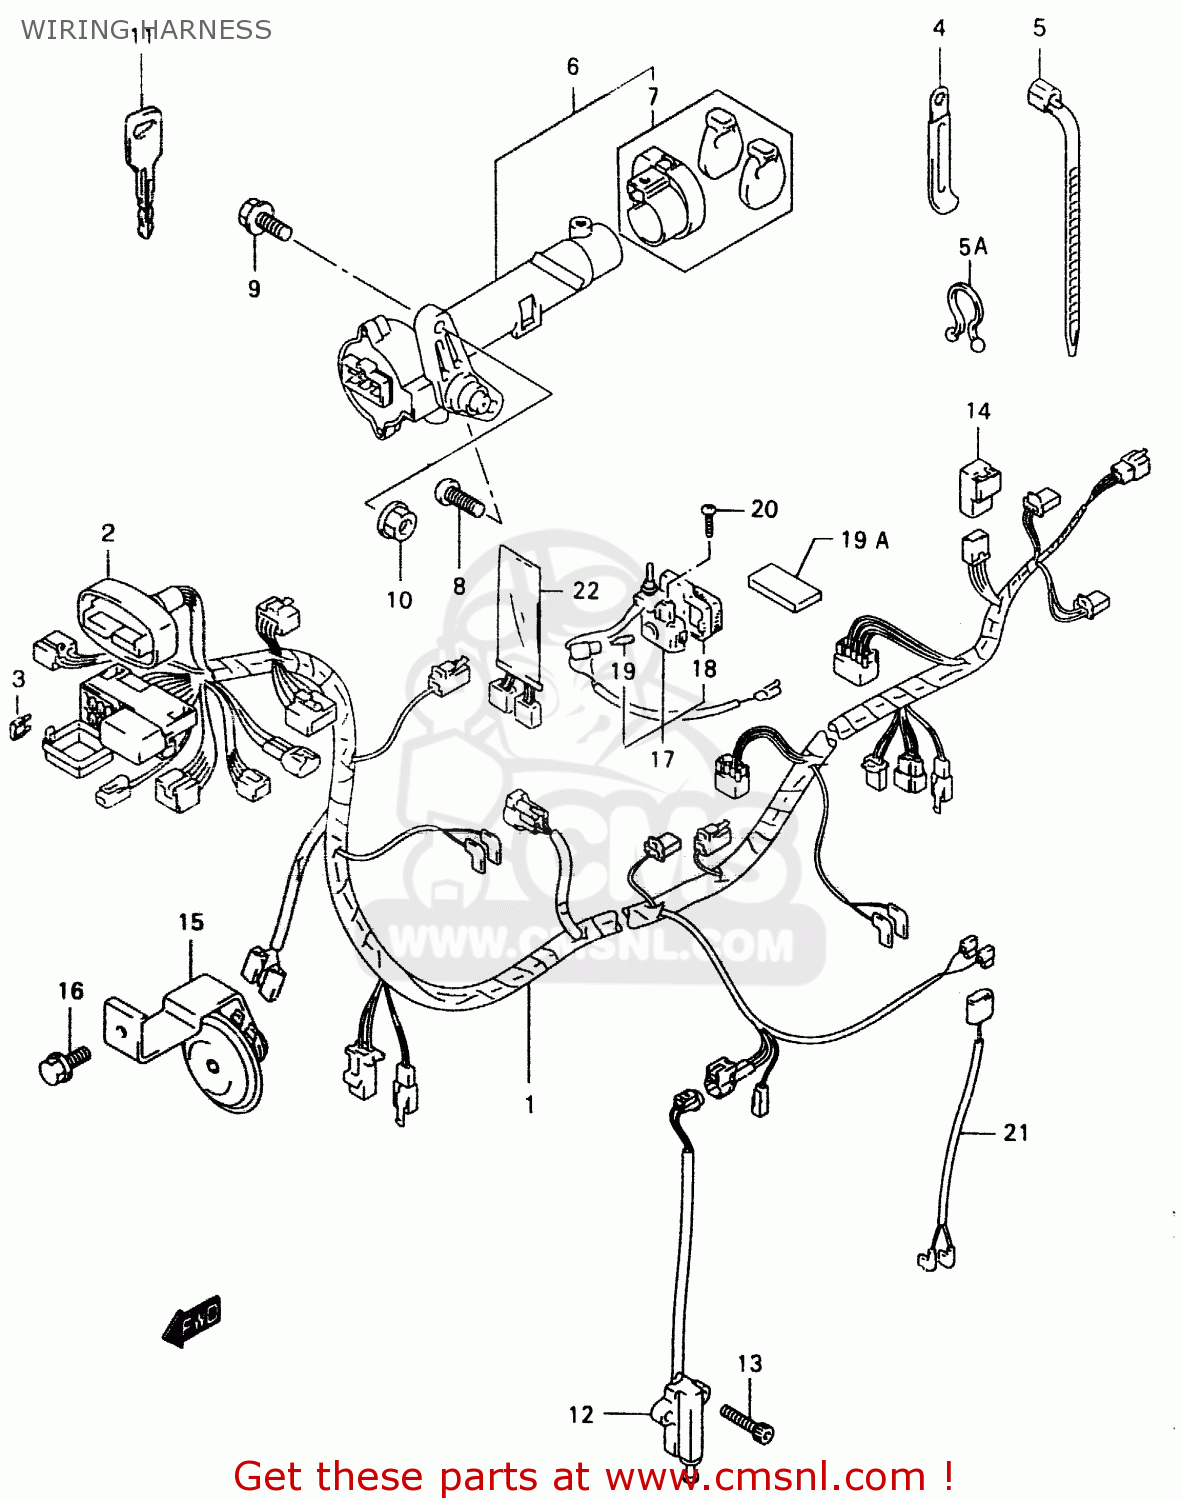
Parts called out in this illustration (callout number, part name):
1	HARNESS, WIRING
2	BOOT,METER COUPLER
3	FUSE(10A)
4	CLAMP(L:80)
5	CLAMP(L:125)
5A	CLIP(ID:11.5)
6	LOCK ASSY,STEE
7	CAP,ST'RNG LOC
8	SCREW(6X20)
9	BOLT
10	NUT
11	KEY,BLANK(TYPE:C)
12	SWITCH ASSY,SIDE STAND
13	SCREW
14	RELAY ASSY
15	HORN ASSY
16	BOLT
17	LAMP,TRUNK BOX
18	LENS
19	BULB(13.5V,2W,A7427)
19A	TAPE
20	SCREW, TRUNK BOX
21	WIRE,IGNITION COIL LEAD
22	WIRE,PTC RESISTOR
